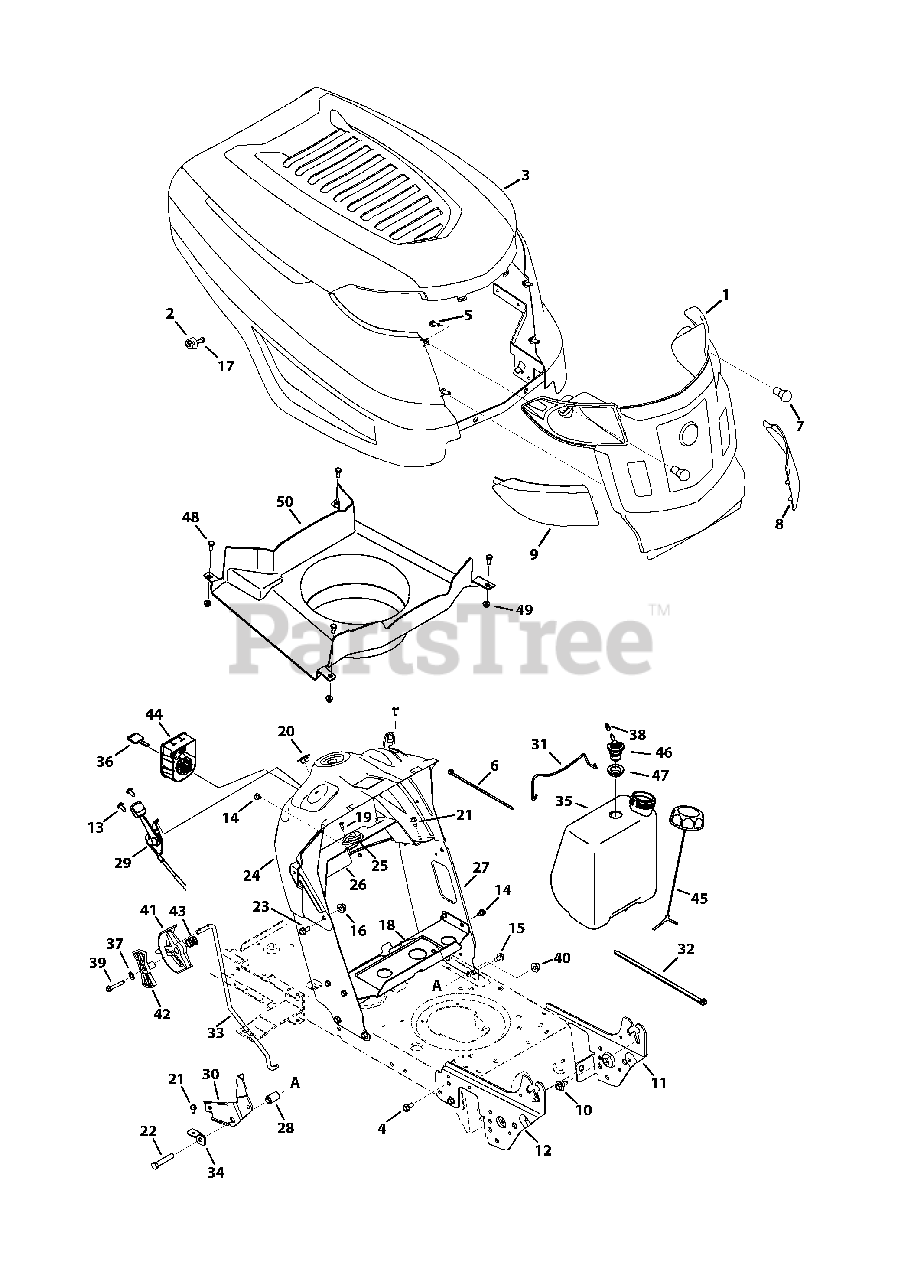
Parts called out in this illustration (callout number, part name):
1	Grill Assembly, Troy-Bilt
2	K-Style Bumper
4	Screw, 5/16-18 x .750
5	Screw, 1/4-15 x .750
6	Cable Tie
9	Right Lens
10	Shoulder Screw, 5/16-18 x .43 x .29
11	Left Support Pivot Bracket
12	Right Support Pivot Bracket
13	Screw, 1/4-20 x .500
14	Screw, 1/4-20 x .500
15	Screw, 5/16-18 x .625
16	Flangelock Nut, 5/16-18
17	Screw, #12-16 x 1.25
18	Gas Tank Support Bracket
19	Screw, #10-16 x .500
20	Choke Plug
21	Tap Screw, 1/4-20, 0.625
22	Hex Screw, 3/8-16 x 2.0
23	Hex Screw, 5/16-18 x .625
24	Dash, Upper
25	Bearing, .628 ID x 1.36
26	Bracket, Steering Support
27	Dash, Lower
28	Flange Spacer, .390 x .671 x 1.095
29	Throttle/Choke Cable
30	Speed Latch - No RMC
31	Battery Assembly Rod
32	Cable Tie
33	Speed Control Rod
34	Speed Latch Tab
35	1.36 Gallon Fuel Tank
36	Key, Assembly
37	Lock Washer, 1/4
38	Hose Vent, 3/16 EPA
39	Hex Washer Screw, 1/4-20 x 1.50
40	Flangelock Nut, 3/8-16
41	Shift Lever
42	Index Control
43	Compr. Spring, .72 OD x .78
44	3 Position Key Switch
45	Fuel Cap, 2.25"
46	Rollover Valve
47	Rubber Grommet, 23 x 3.55
48	Hex Cap Screw, 1/4-20 x .62 GR5
49	Flangelock Nut, 1/4-20
